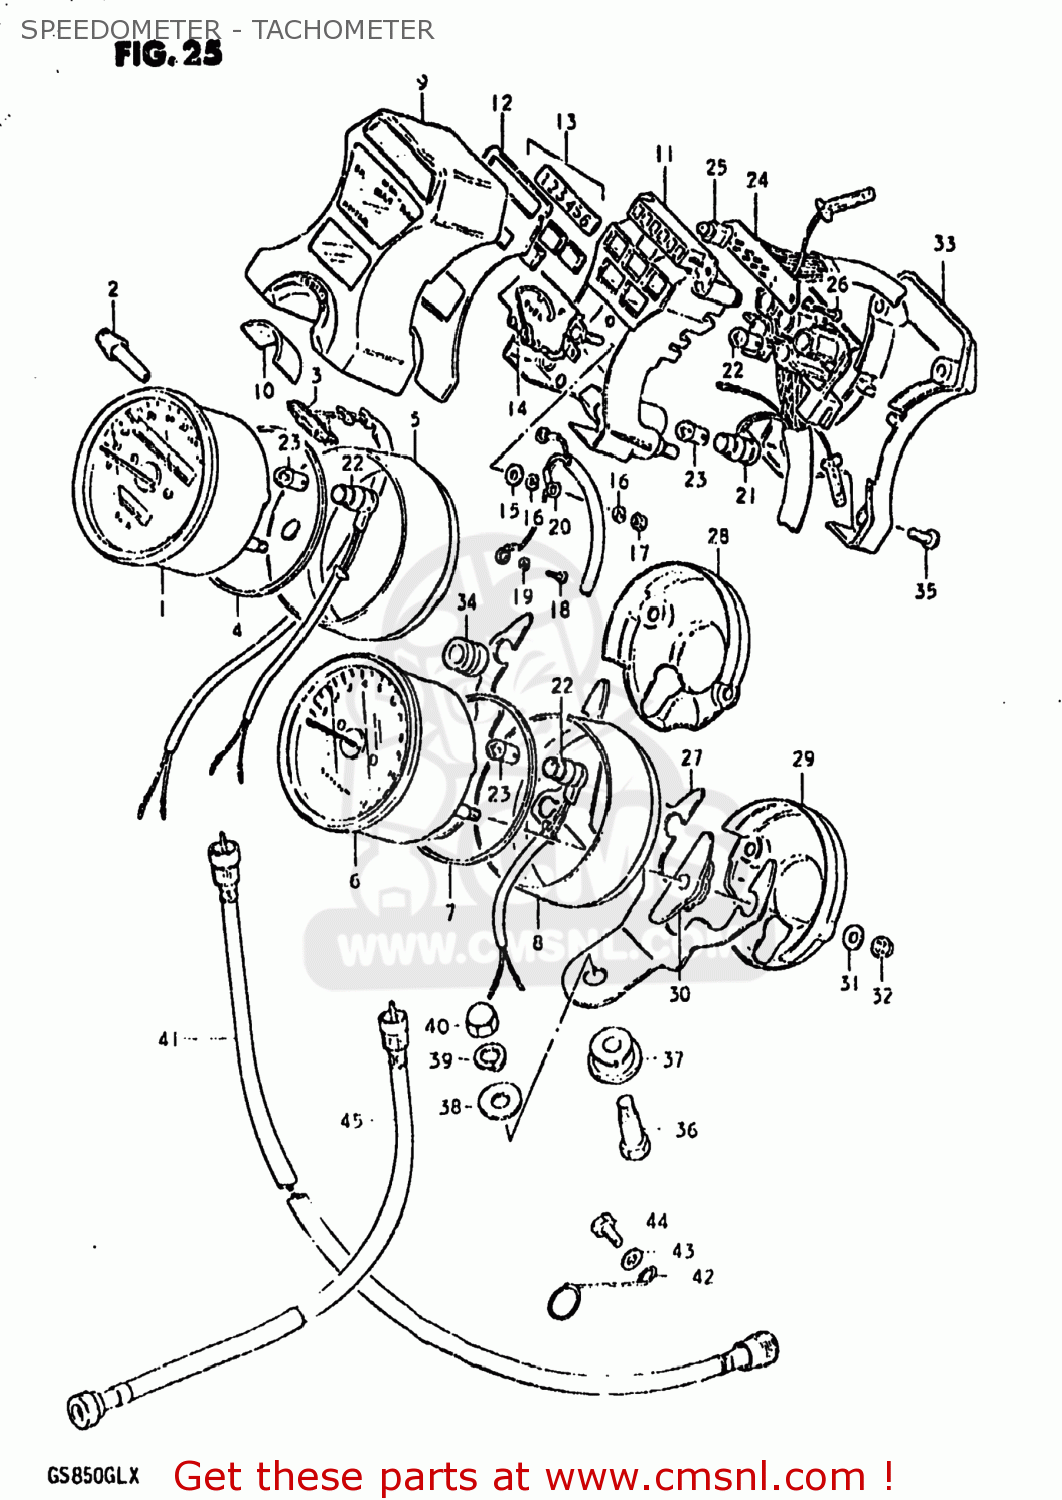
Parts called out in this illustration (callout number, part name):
1	METER,SPEEDOMETER
2	KNOB
3	WIRE,LEAD SWITCH
4	CUSHION
5	COVER,SPEEDOMETER
6	TACHOMETER
7	CUSHION
8	COVER,TACHOMETER
9	CASE,PILOT BOX,OUTER
10	SEAL,IGNITION SWITCH
11	CASE, PILOT BOX INNER
12	PLATE,PILOT BOX
13	LENS SET,PILOT
14	METER,FUEL
15	WASHER
16	LOCK WASHER
17	NUT
18	SCREW
19	LOCK WASHER
20	LEAD WIRE, FUELMETER
21	SOCKET
22	SOCKET,METER
23	BULB(12V3.4W,STANLEY,A72A)
24	SOCKET,GEAR INDICATOR
25	BULB(14V1.12W)
26	SCREW
27	BRACKET,COMBINATION METER
28	ORNAMENT,SPEEDOMETER
29	COVER,TACHOMETER
30	CUSHION,METER
31	WASHER
32	NUT
33	COVER,PILOT BOX,UNDER
34	CUSHION,PILOT BOX
35	SCREW,PILOT BOX
36	BOLT
37	CUSHION,METER
38	WASHER(8.5X23X1.2)
39	LOCK WASHER
40	NUT
41	CABLE ASSEMBLY,SPEEDOMETER
42	GUIDE,SPEEDOMETER CABLE
43	WASHER
44	BOLT, UPPER
45	CABLE ASSEMBLY,TACHOMETER
